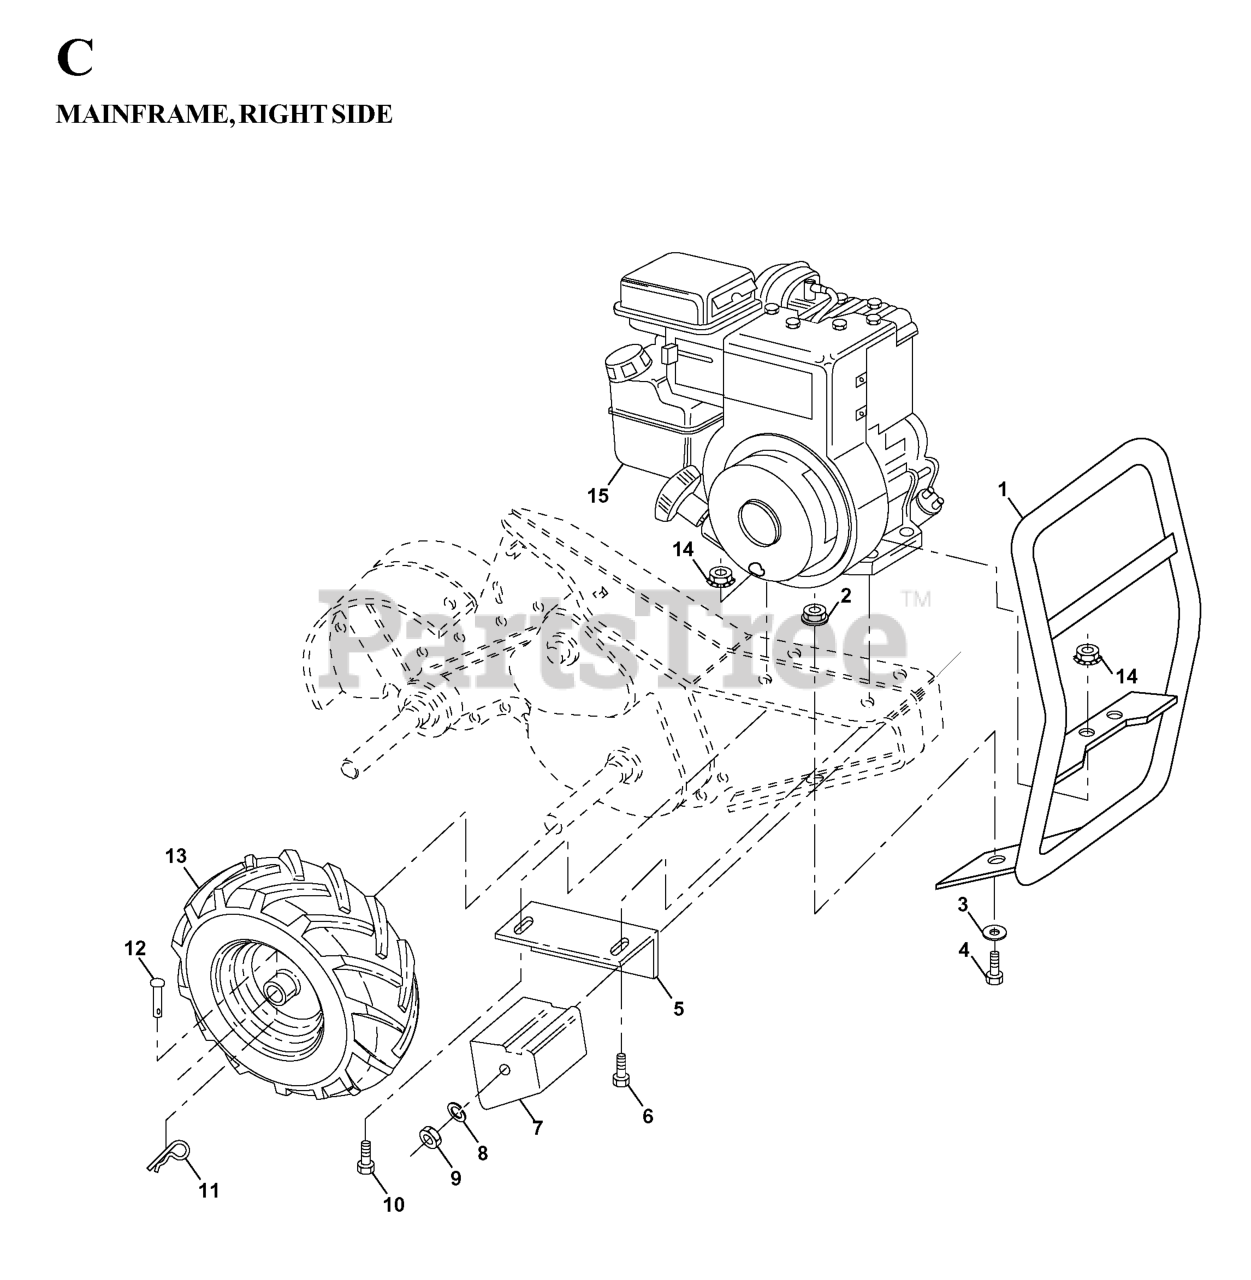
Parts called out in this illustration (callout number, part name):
1	BUMPER ASM TILLER
2	LOCKNUT-FLANGE 5/16-18
3	WASHER
4	BOLT
5	DNO BRACKET RH CRT
6	Bolt Fin Hex 5/16 - 18 Unc x 2 Gr. 2
7	COUNTERWEIGHT, RH
8	WASHER, LOCK 3/8
9	NUT.HEX.3/8-16UNC
10	BOLT
11	RETAINER M
12	RIVET,DRILLED
13	TIRE.16X4-8.CHEVRON.TILLER
14	NUT
532124366	RIM
532124718	VALVE STEM LT
